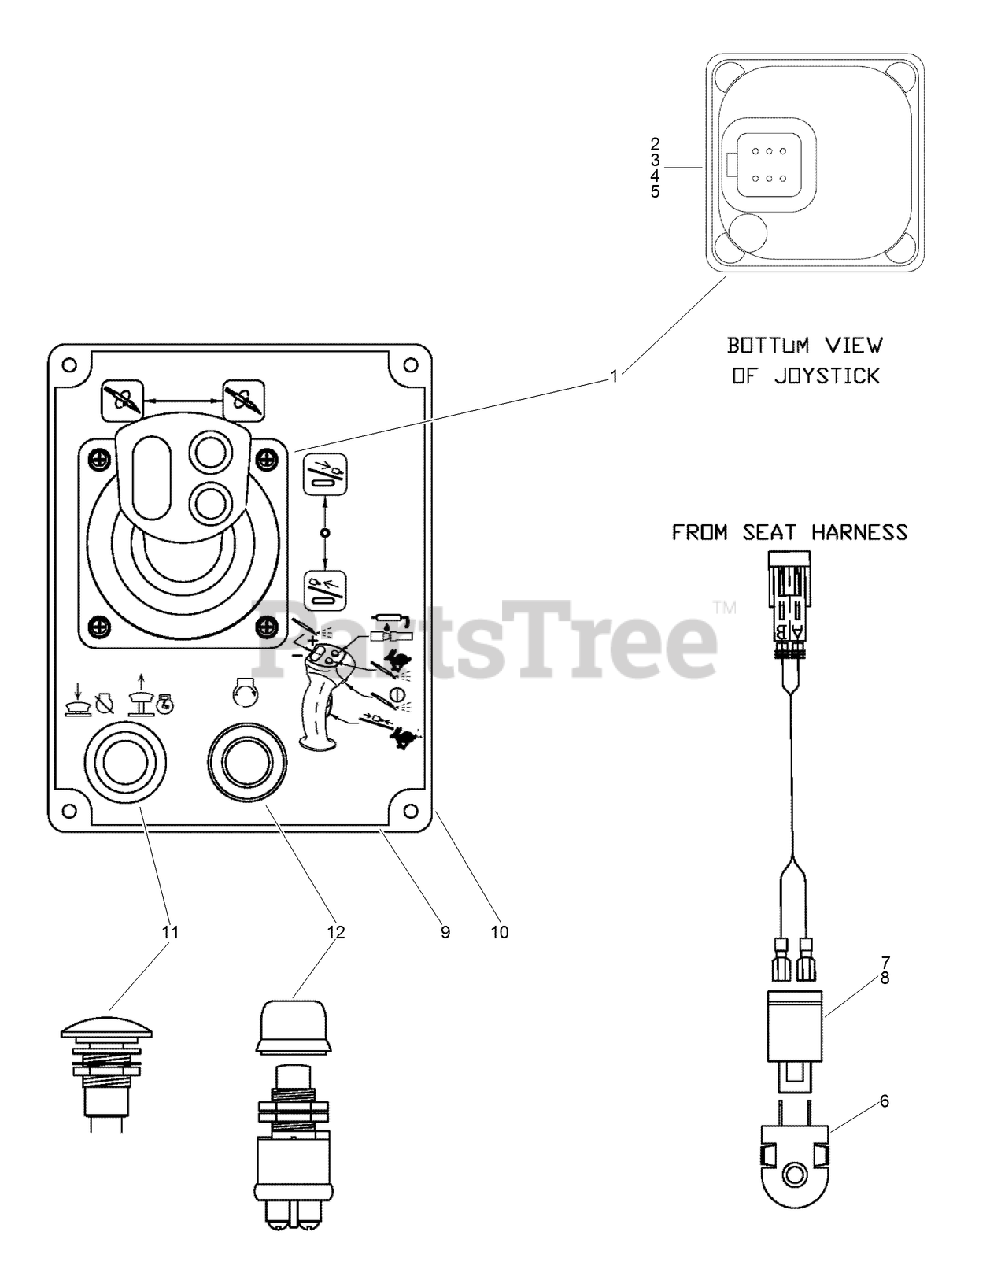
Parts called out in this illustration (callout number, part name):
1	JOYSTICK-CARRIAGE
2	CONNECTOR - 6 Pin
3	WEDGE - Locking
4	SEALING PLUG - 20 AWG, Deutsch
5	SOC CONTACT - 20 AWG, Deutsch
6	SWITCH - Seat
7	HOUSING - Connector
8	CONTACTS - Socket
9	OVERLAY - 32GB9711L
10	PLATE - Mounting
11	BUTTON-PUSH, RED MUSHROOM
12	SWITCH - Pushbutton, Ether
